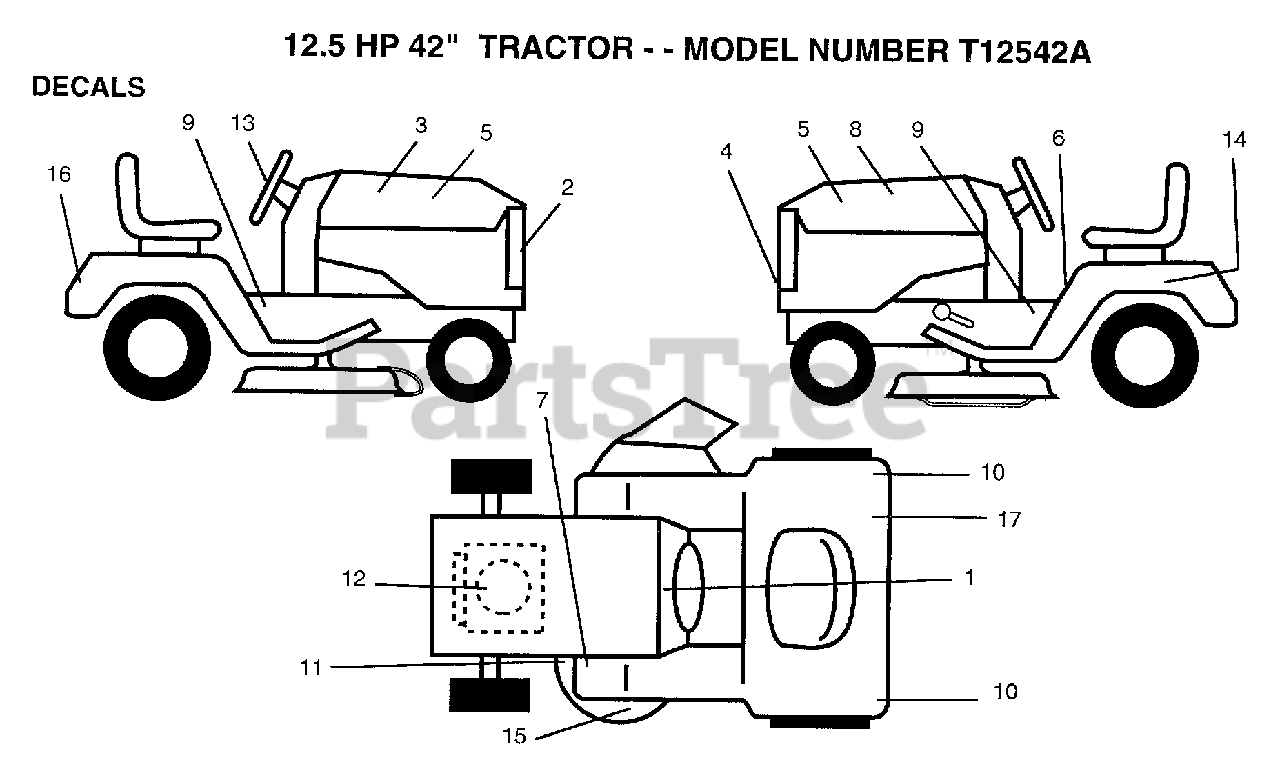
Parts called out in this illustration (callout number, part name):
3	DECAL.HOOD.RH
4	DECAL.STRIPE.GR
5	"DECAL, HP HOOD"
6	DECAL
9	CHASSIS DECAL
10	REFLECTOR-TAIL YT
11	DECAL
14	DECAL
16	DECAL.FENDER
